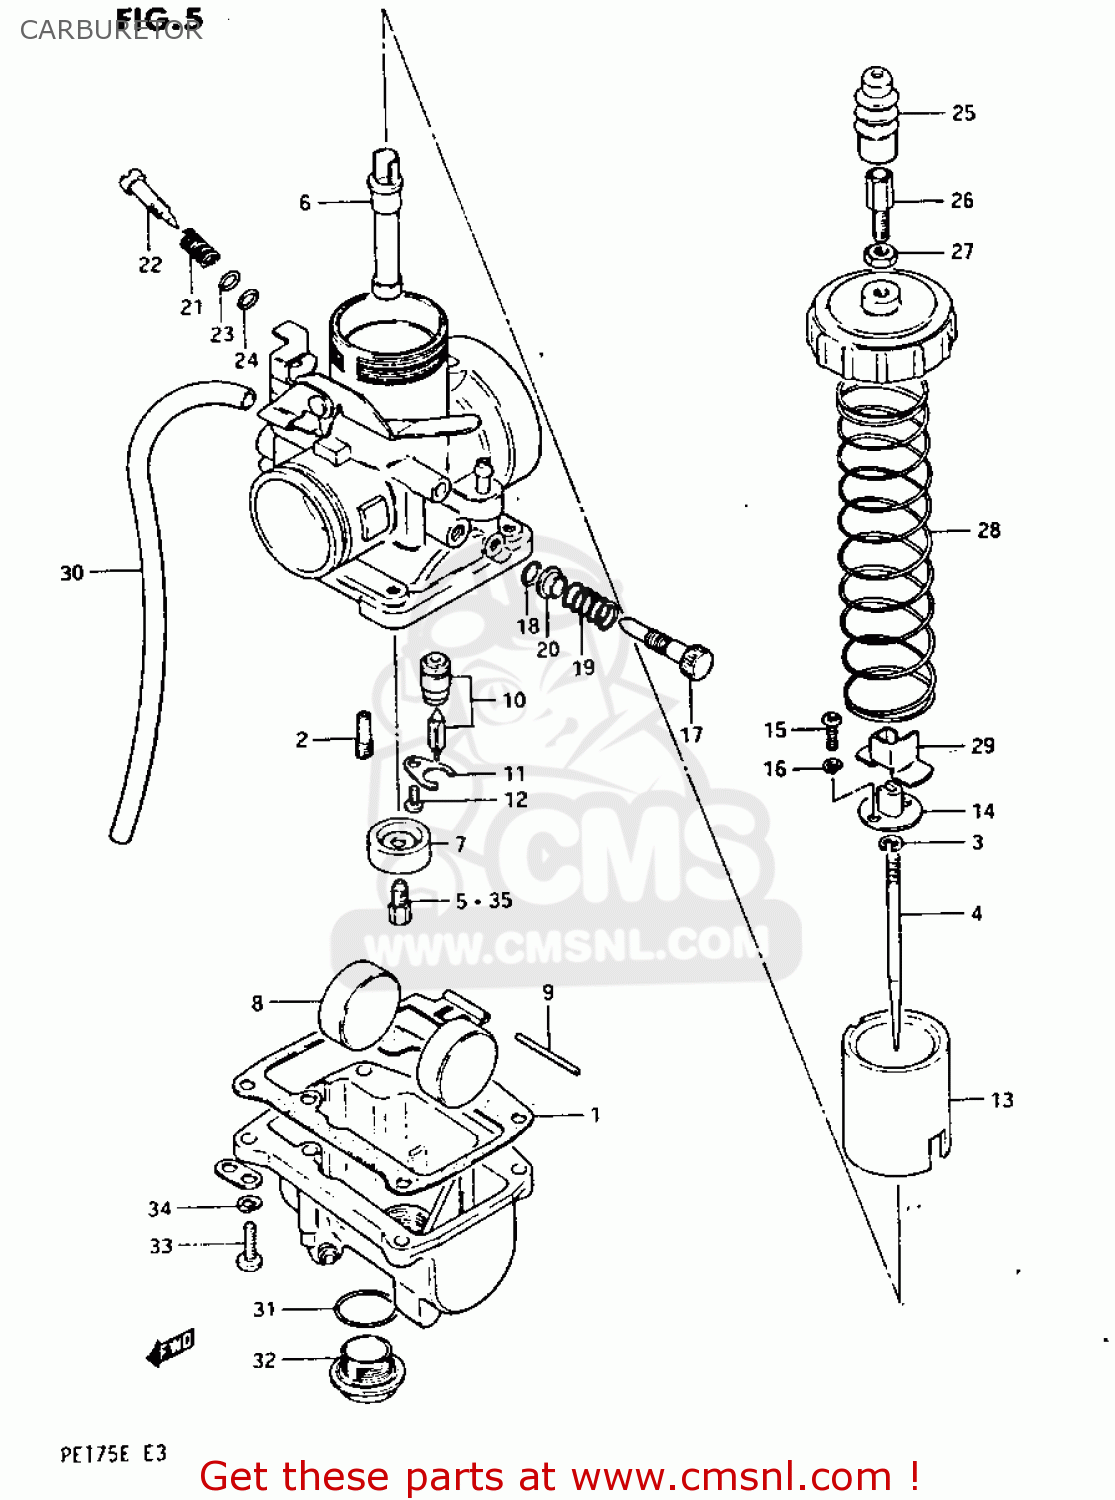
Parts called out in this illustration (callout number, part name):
1	CARBURETOR ASSEMBLY (VM34)
2	JET,PILOT(25)
3	CLIP
4	NEEDLE,JET
5	JET,MAIN(250)
6	JET,NEEDLE
7	RING,MAIN JET FIXING
8	FLOAT
9	PIN,FLOAT
10	VALVE ASSY,NEEDLE
11	PLATE
12	SCREW 4X6
13	VALVE,THROTTLE
14	CONNECTOR
15	SCREW
16	WASHER,LOCK
17	SCREW,THROTTLE STOP
18	O RING
19	SPRING,THROTTLE STOP
20	COVER
21	SPRING
22	SCREW,PILOT AIR
23	WASHER,PILOT AIR SCREW
24	O RING
25	CAP,CABLE ADJUSTER
26	ADJUSTER,CABLE
27	NUT
28	SPRING,THROTTLE VALVE RETURN
29	COVER,HOLDER
30	HOSE
31	O RING(D:1.5,ID:19.5)
32	PLUG
33	SCREW
34	LOCK WASHER
35	JET
